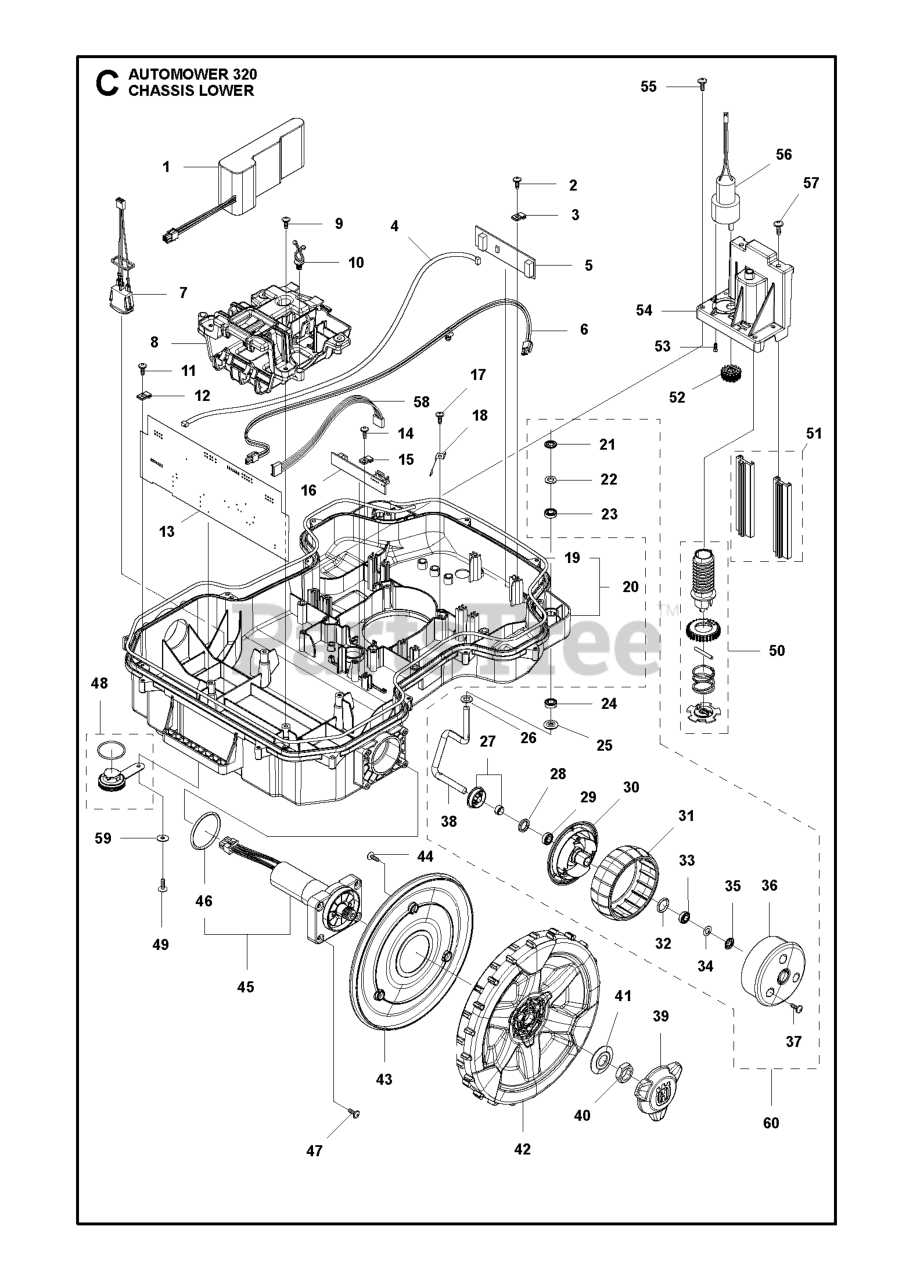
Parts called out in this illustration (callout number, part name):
1	BATTERY LI-ION
2	SCREW 14MM
4	LOOM LOOP SENSOR
5	PRINTED CIRCUIT ASSY PCBA LOOP
7	LOOM ON/ OFF
9	SCREW ITXPANT
10	HOLDER TWIST LOCK
11	SCREW 14MM
14	SCREW 14MM
17	SCREW 14MM
18	SPRING GUIDE HEIGHT ADJUSTMENT
19	SEALING STRIP
19	SEALING STRIP CHASSIS 10 PCS
21	LOCK WASHER PUSH-ON TYPE P 8 S
22	WASHER DIN 988 13X8X0.5
23	BALL BEARING SINGLE ROW S688
24	BALL BEARING SINGLE ROW S688
25	WASHER FRONT WHEEL CENTER HOLE
26	WASHER DIN 988 13X8X0.5
27	SHIELD KIT
28	SEALING 12X18X3
29	BALL BEARING SINGLE ROW S688
30	WHEEL FRONT WHEEL INSIDE
31	WHEEL RUBBER TYRE
32	O-RING 2,62X15,54
33	BALL BEARING SINGLE ROW S688
34	WASHER DIN 988 13X8X0.5
35	LOCK WASHER PUSH-ON TYPE P 8 S
36	WHEEL FRONT WHEEL OUTSIDE
37	SCREW 14MM
38	SPINDLE SPINDLE FRONT WHEEL RI
39	HUB CAP REAR WHEEL NO CENTER P
40	HEXAGON THIN NUT
41	WASHER WASHER REAR WHEEL 16X40
42	WHEEL ASSY D249 HVA LIGHT GREY
43	COVER REAR WHEEL
44	SCREW 14MM
45	MOTOR KIT DRIVE WHEEL
47	SCREW ITXPANT
49	SCREW 14MM
51	BEARING KIT
55	SCREW 14MM
58	LOOM HEIGHT ADJUSTMENT
60	WHEEL KIT FRONT
